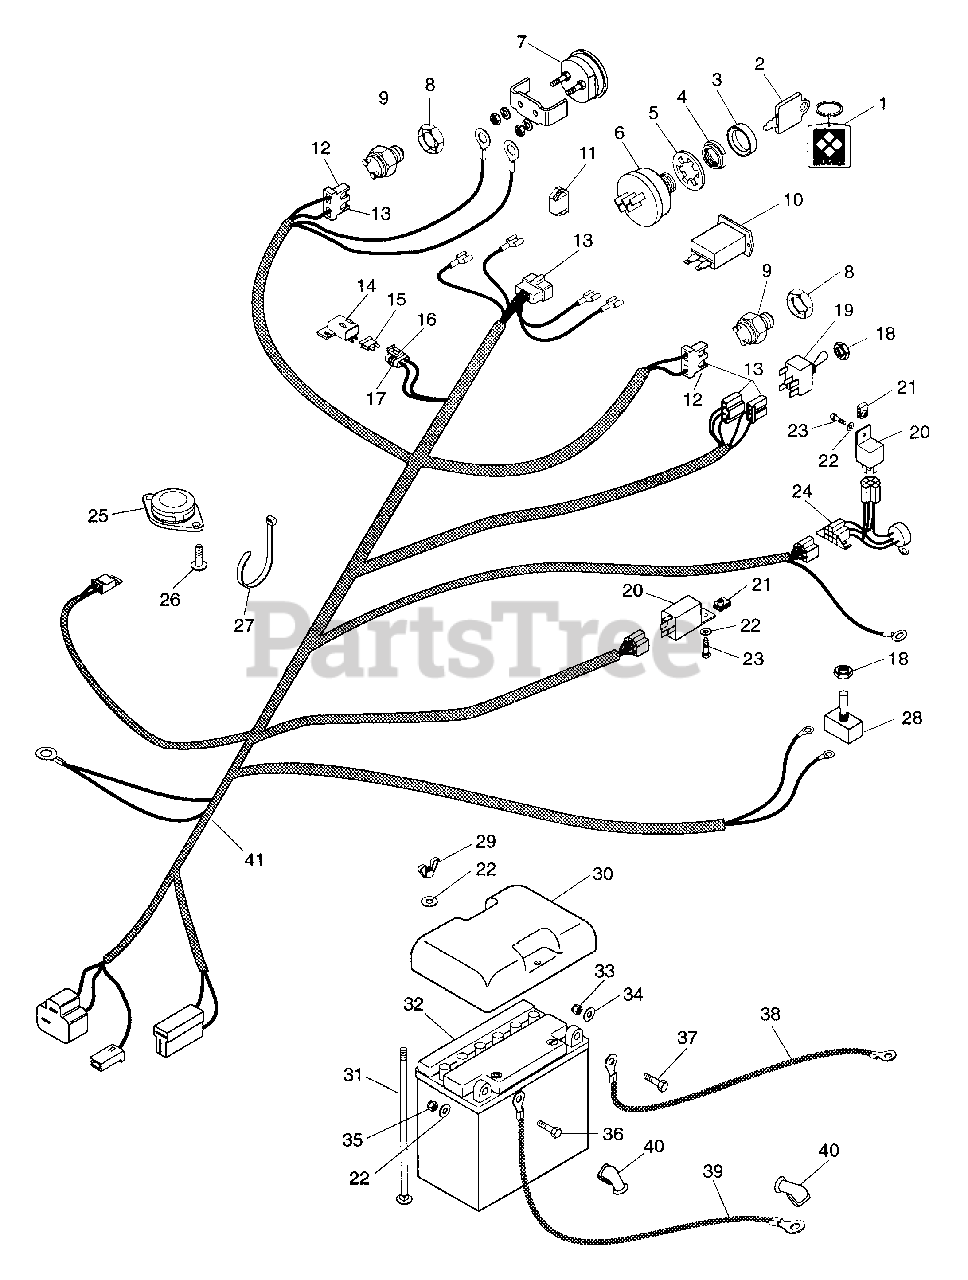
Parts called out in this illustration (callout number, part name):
1	Key Chain
2	Ignition Switch Key
3	Cap-Ignition Switch
4	Nut-Panel .562-24
5	Washer-Lock Internal .563 x .040
6	Ignition Switch
7	Gauge-Ammeter
8	Nut-Stamped .56-18
9	Switch, Neutral Start N.O.
10	Hour Meter
11	Light, Indicator
12	Connector, 2-Wire Switch
13	Terminal
14	Cover
15	Fuse, 25 AMP
16	Assembly, Connector Weather Tight
17	Terminal, For 10-12 Ga Wire
18	Nut .50-27
19	Switch Assembly
20	Relay
21	Nut-Speed .25-20
22	Washer-Flat-Steel .382 x 1.25 x .134
23	Bolt-Hex .25-20 x .63
24	Module, Time Delay
25	Seat Switch
26	Screw-Machine .25-20 x .50
27	Tie Wrap, Black
28	Switch Assembly
29	Nut-Wing .250-20
30	Cover, Battery
31	Bolt-Round Head Square Neck .25-20 x 7.00
32	12 Volt Battery
33	Nut-Locking-Nylon .312-18 Grade 2
34	Washer-Flat-Steel .344 x .688 x .065
35	Nut-Locking-Nylon .250-20 Grade 2
36	Bolt-Hex .25-20 x .75 Grade 5
37	Bolt-Hex .31-18 x 1.00 Grade 5
38	Cable, Negative Battery
39	Cable, Battery To Solenoid
39	Cable, Positive Battery
40	Boot Insulator
41	Harness, Wiring
